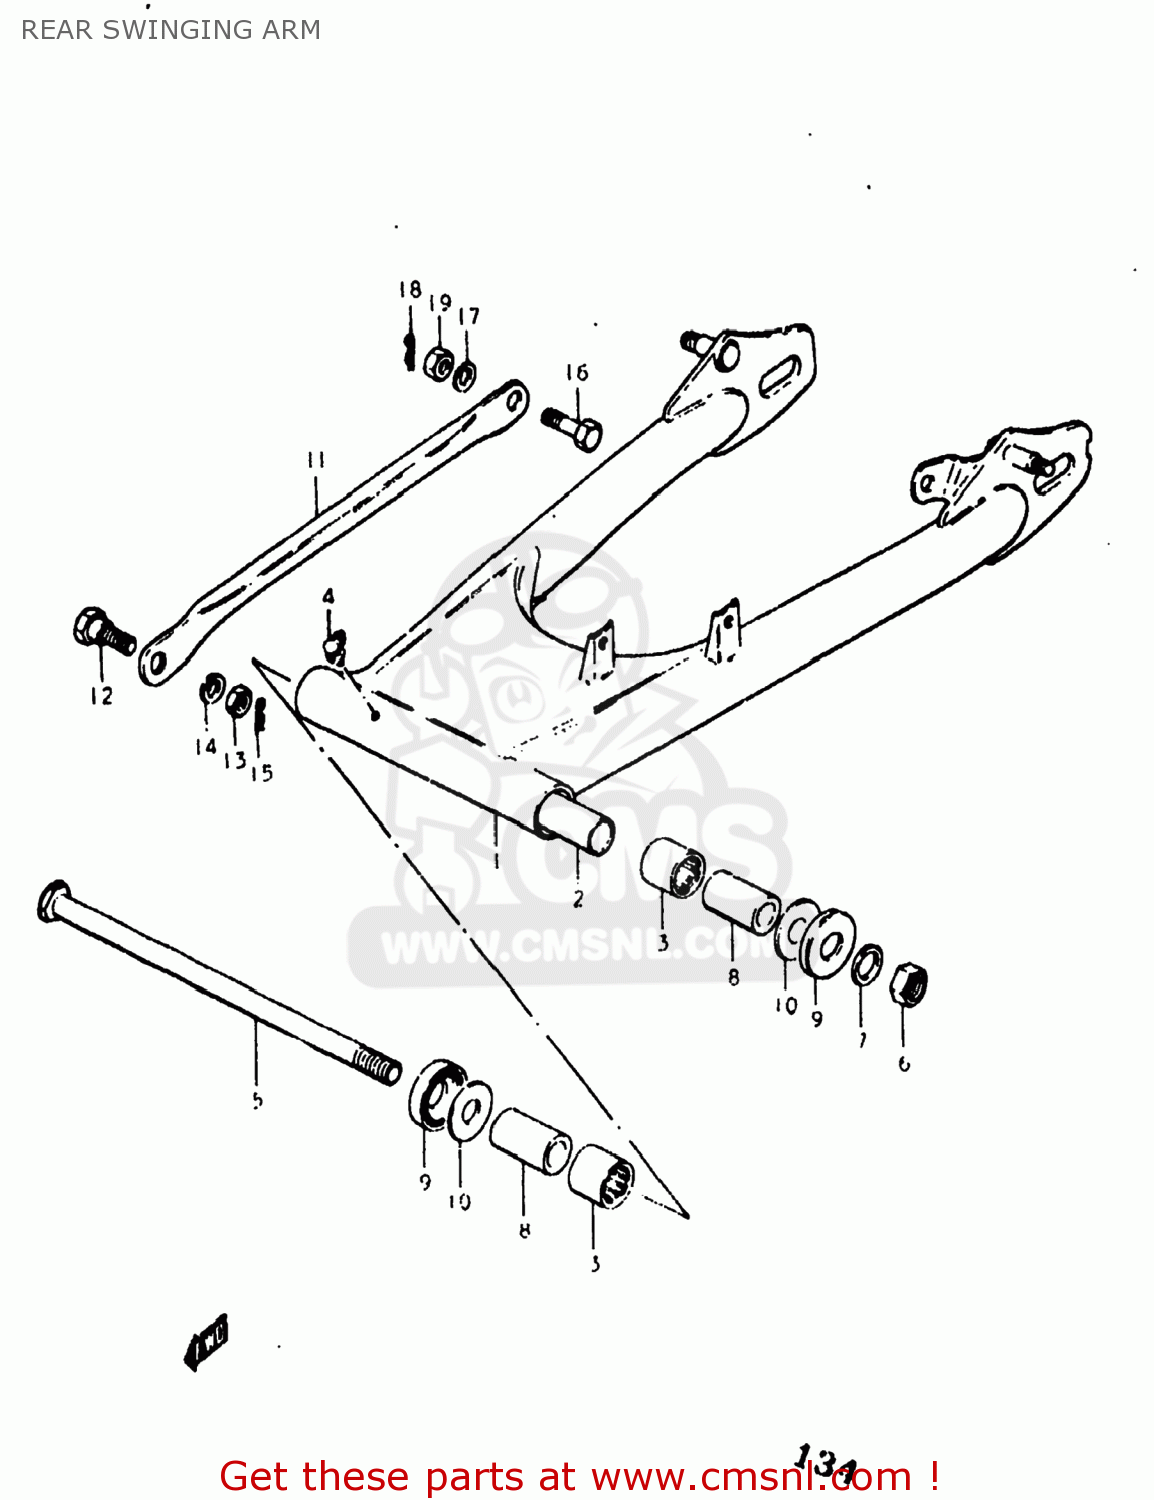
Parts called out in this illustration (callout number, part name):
1	SWING ARM ASSEMBLY,REAR
2	SPACER,SWING ARM,CENTER
3	BEARING(22X29X30)
4	NIPPLE,GREASE
5	SHAFT,REAR SWING ARM
6	NUT
7	WASHER
8	SPACER,RR SWGARM PIVOT
9	COVER,REAR SWING ARM DUST
10	WASHER(14.2X34X1)
11	TORQUE LINK,REAR
12	BOLT(10X24.5)
13	NUT
14	LOCK WASHER
15	CLIP
16	BOLT(10X31)
17	LOCK WASHER
18	CLIP
19	NUT
